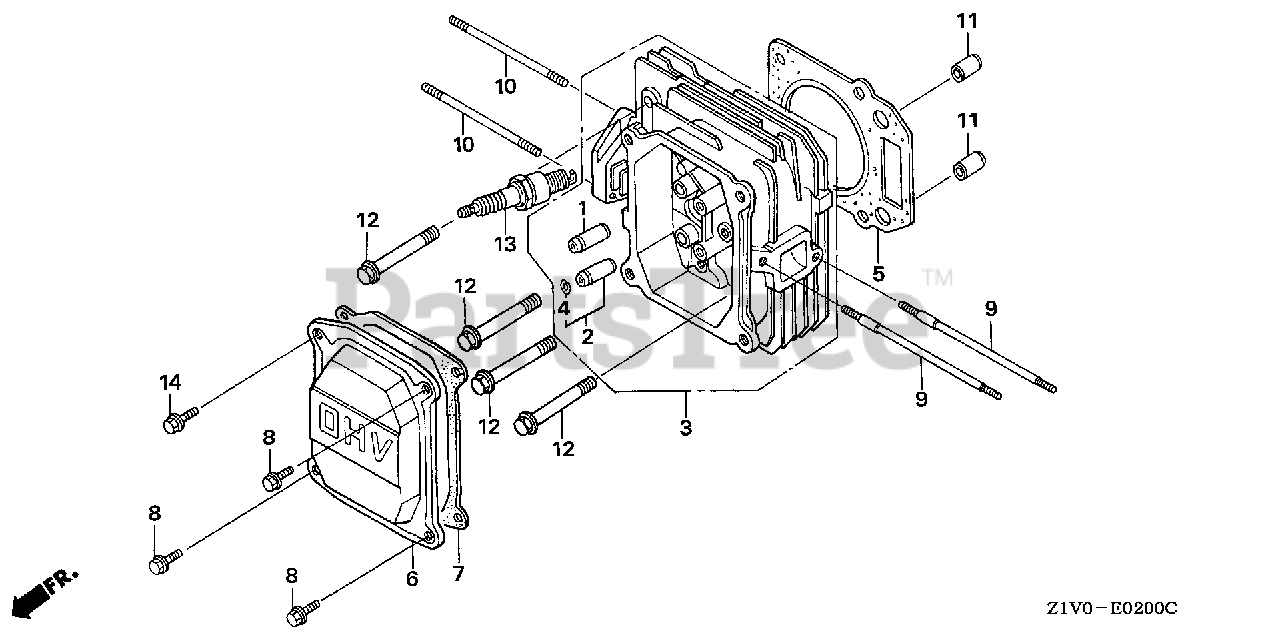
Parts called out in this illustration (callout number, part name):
1	GUIDE, VALVE (OVER SIZE)
2	GUIDE, EX. VALVE (OVER SIZE)
3	CYLINDER HEAD
4	CLIP, VALVE GUIDE
5	GASKET, CYLINDER HEAD
6	COVER, HEAD
7	GASKET, HEAD COVER
8	BOLT, FLANGE (6X12) (CT200)
9	BOLT, STUD (6X109)
10	BOLT, STUD (6X85)
11	PIN, DOWEL (10X16)
12	BOLT, FLANGE (8X50)
13	SPARK PLUG (BPR4ES) (NGK)
13	SPARK PLUG (W14EPR-U) (DENSO)
13	SPARK PLUG (BPR5ES) (NGK)
13	SPARK PLUG (W16EPR-U) (DENSO)
13	SPARK PLUG (BPR6ES) (NGK)
13	SPARK PLUG (W20EPR-U) (DENSO)
14	BOLT, FLANGE (6X14) (CT200)
